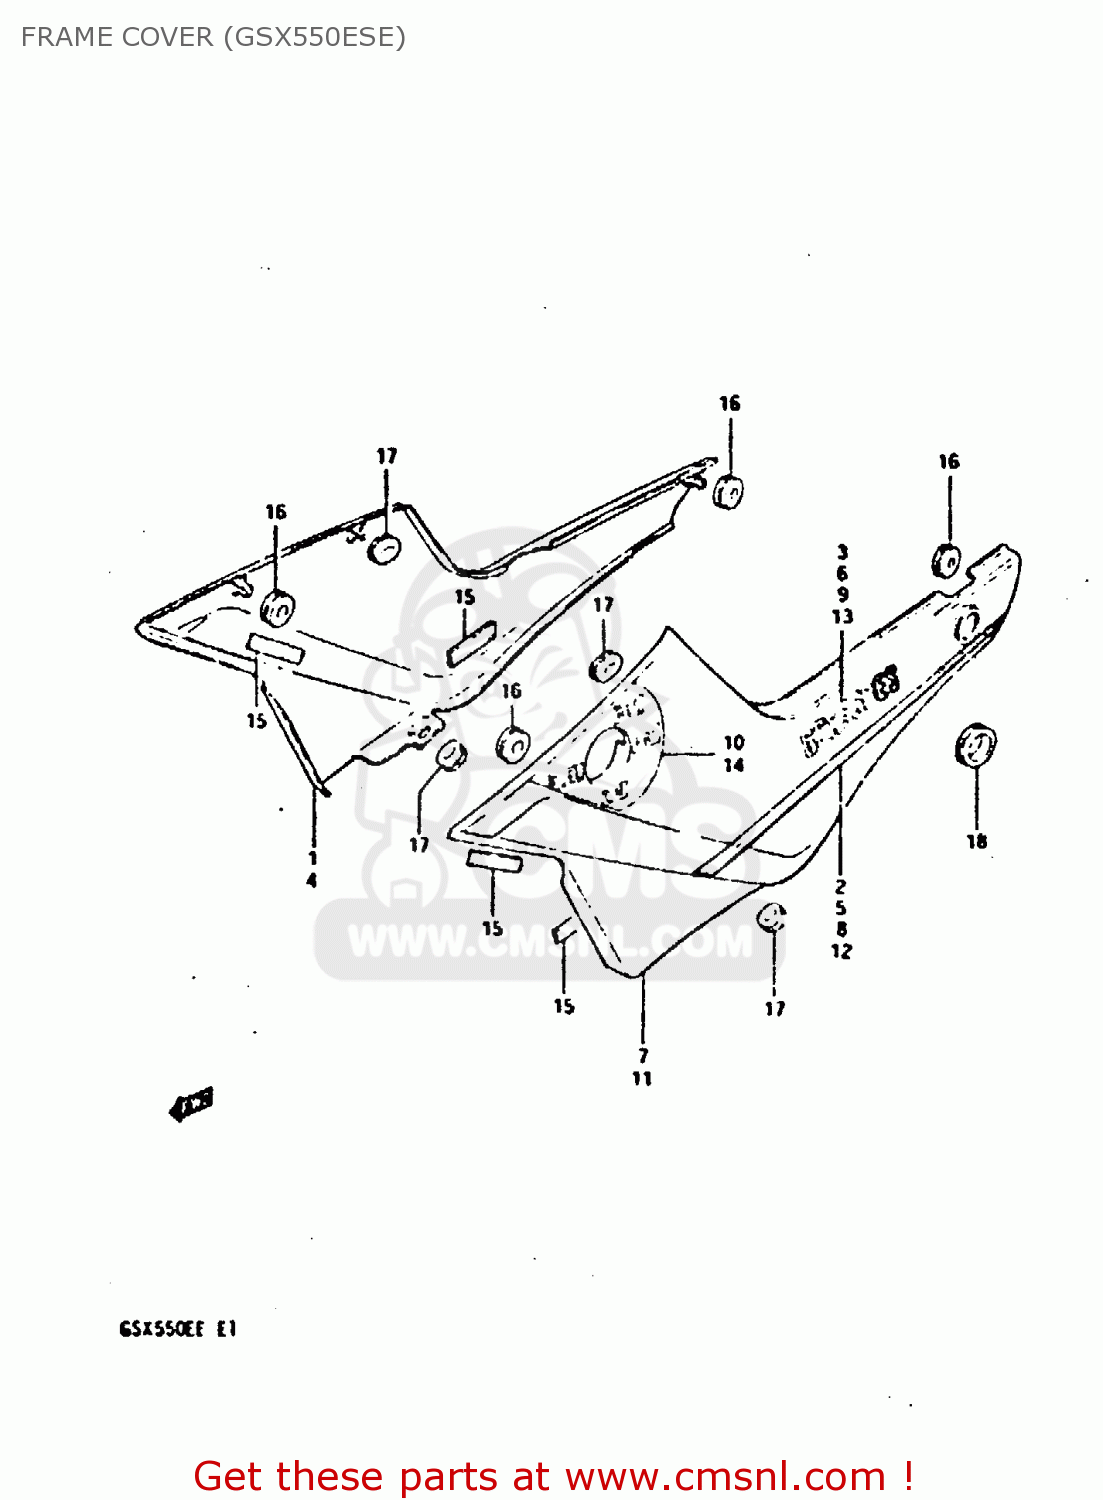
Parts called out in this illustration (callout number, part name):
1	COVER, FRAME RH
2	TAPE SET,FRAME COVER,RIGHT
3	EMBLEM
4	COVER, FRAME RH
5	TAPE SET, FRAME COVER RH
6	EMBLEM
7	COVER, FRAME LH
8	TAPE SET,FRAME COVER
9	EMBLEM
10	EMBLEM,FUEL COCK
11	COVER, FRAME LH
12	TAPE SET, FRAME COVER LH
13	EMBLEM
14	EMBLEM,FUEL COCK
15	RUBBER,FRAME COVER
16	CUSHION
17	CUSHION
18	GROMMET,SEAT LOCK HOLE
